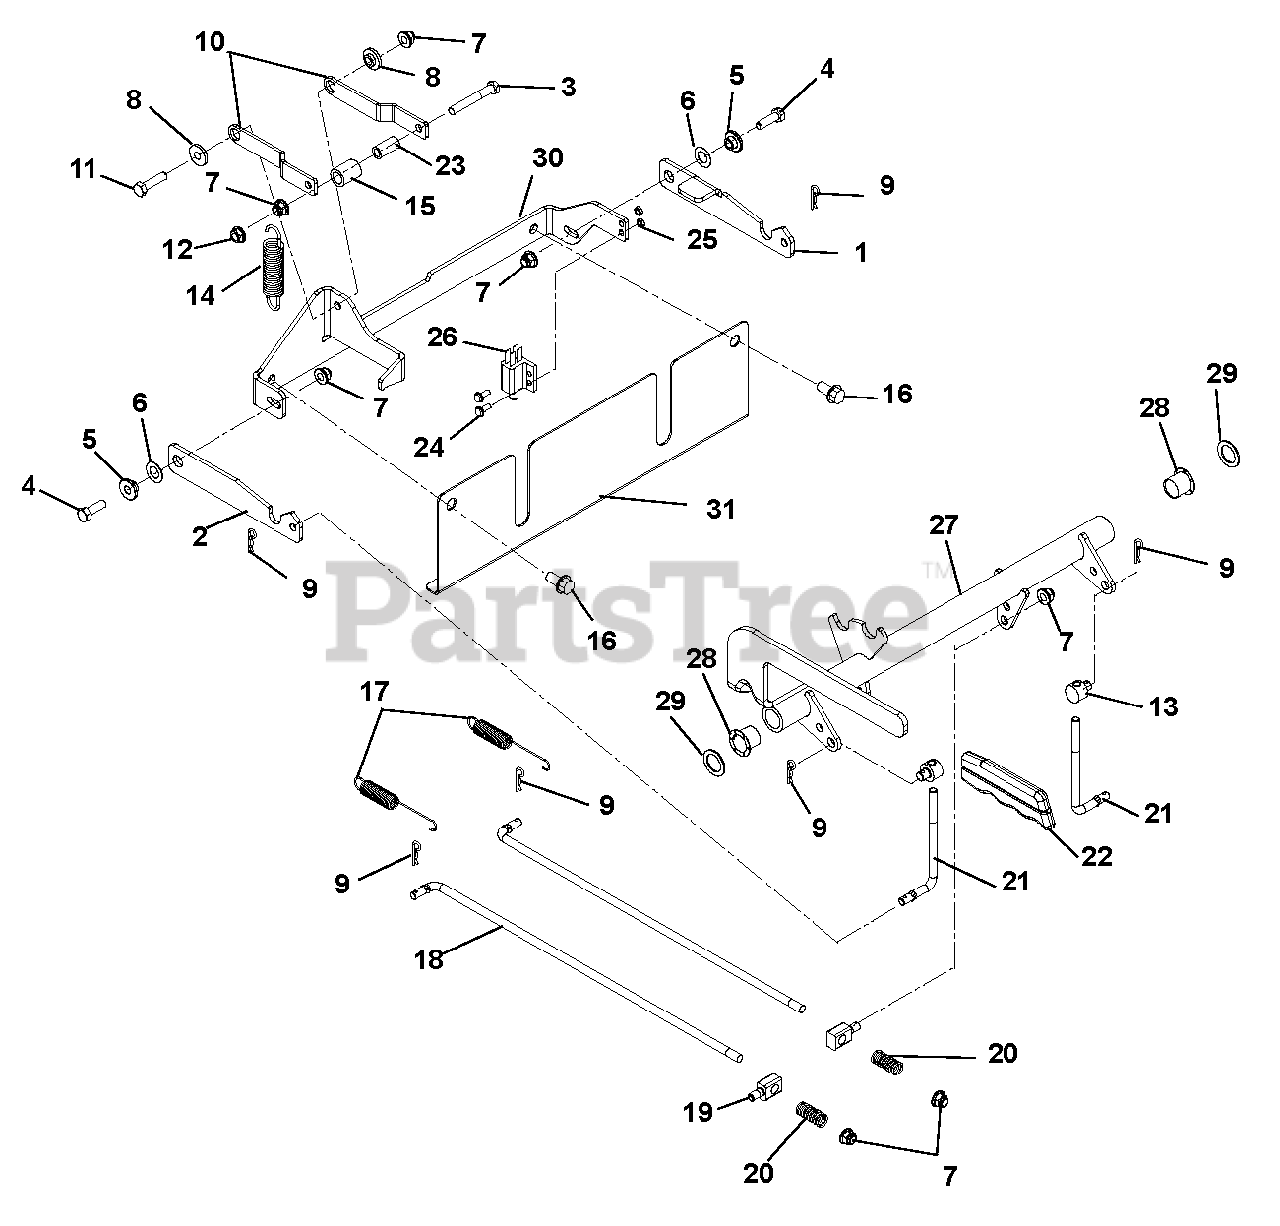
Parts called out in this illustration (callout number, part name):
1	Link, Brake Interlock
2	Interlock, Brake
3	Bolt, Hex .31-18 x 2.25 Grade 5
4	Bolt, Hex .31-18 x 1.00 Grade 5
5	Bushing, Flange .312 x .500 x .344 x .880
6	Washer, Flat Steel .505 x .875 x .024
7	Nut, Flange Nyloc 5/16-18
8	Shoulder Spacer
9	Pin, Hair Internal .08 x .18 x 1.18
10	Arm, Brake Cam
11	Bolt, Hex .31-18 x 1.25 Grade 5
12	Nut, Locking Top Flange .31-18
13	Trunnion, Brake
14	Spring, Tension .105 x .812 x 3.88
15	Roller, Cam Lock
16	Screw, Tapping .38-16 x .75 Hex Washer Head
17	Spring, Tension .056 x .60 x 4.40
18	Rod, Park Brake
19	Pin, Pivot
20	Spring, Compression
21	Link, Interlock Brake
22	Grip, Park Brake
24	Screw, Machine 10-24 x .75 Hex Washer Head
25	Nut, Locking Nylon 10-24 with Insert
26	Switch, Double Pole
27	Weldment, Brake Shaft
28	Bushing, IGLIDE Clip
29	Washer, Flat Steel .754 x 1.125 x .062
30	Bracket, Brake Mounting
31	Bracket, Lower Finger Guard
